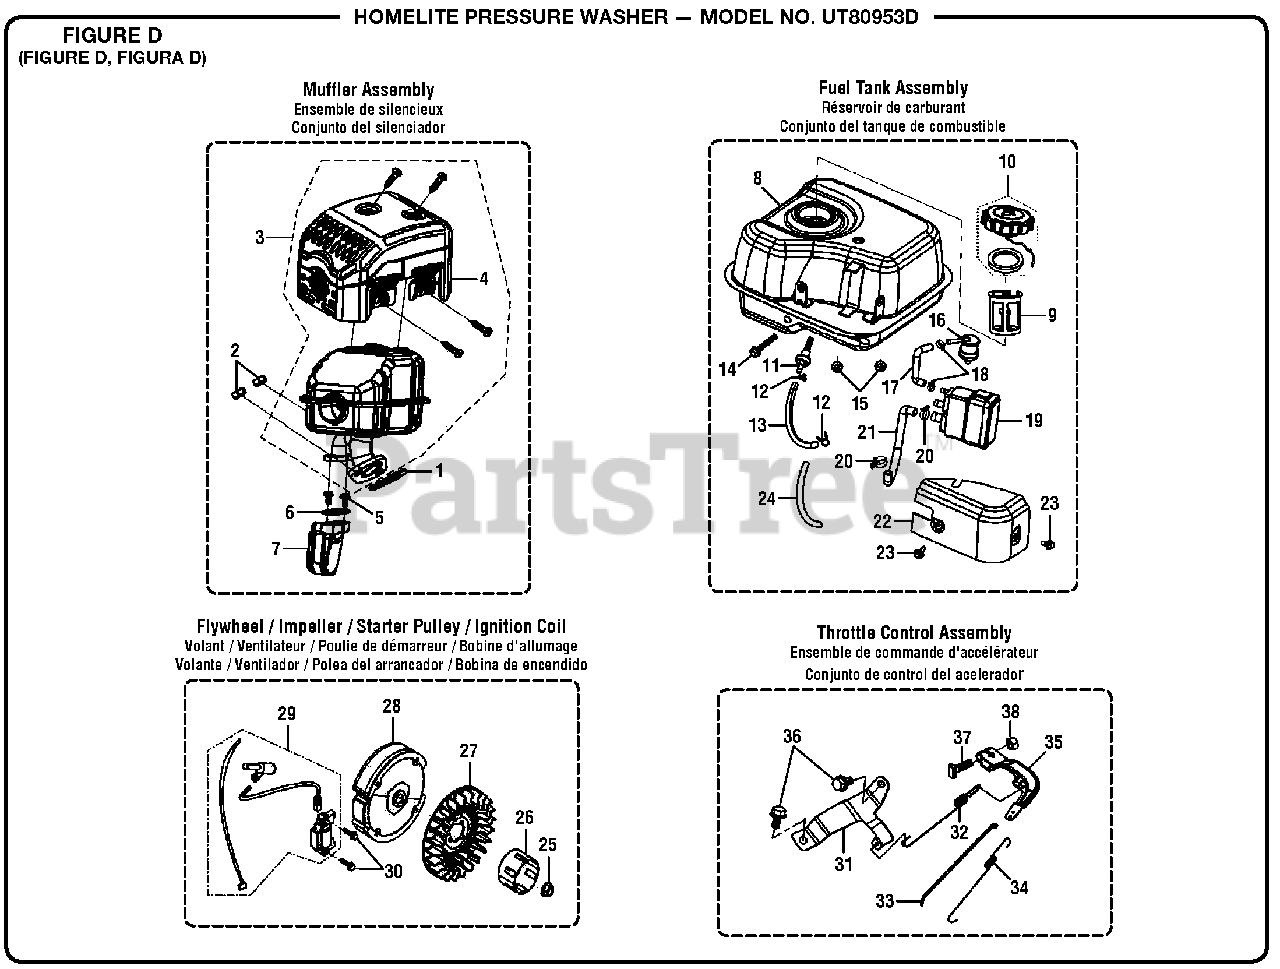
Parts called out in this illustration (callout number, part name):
1	Exhaust Outlet Gasket
3	Muffler Assembly
6	Air Valve Gasket
11	Fuel Filter Assembly
16	Fuel Tank Vapor Vent
19	Carbon Canister
22	Carbon Canister Cover
28	Flywheel Assembly
29	Ignition Coil
31	Throttle Control Assembly
32	Governor Spring
34	Throttle Valve Return Spring
35	Governor Support Assembly
37	Governor Support Bolt
